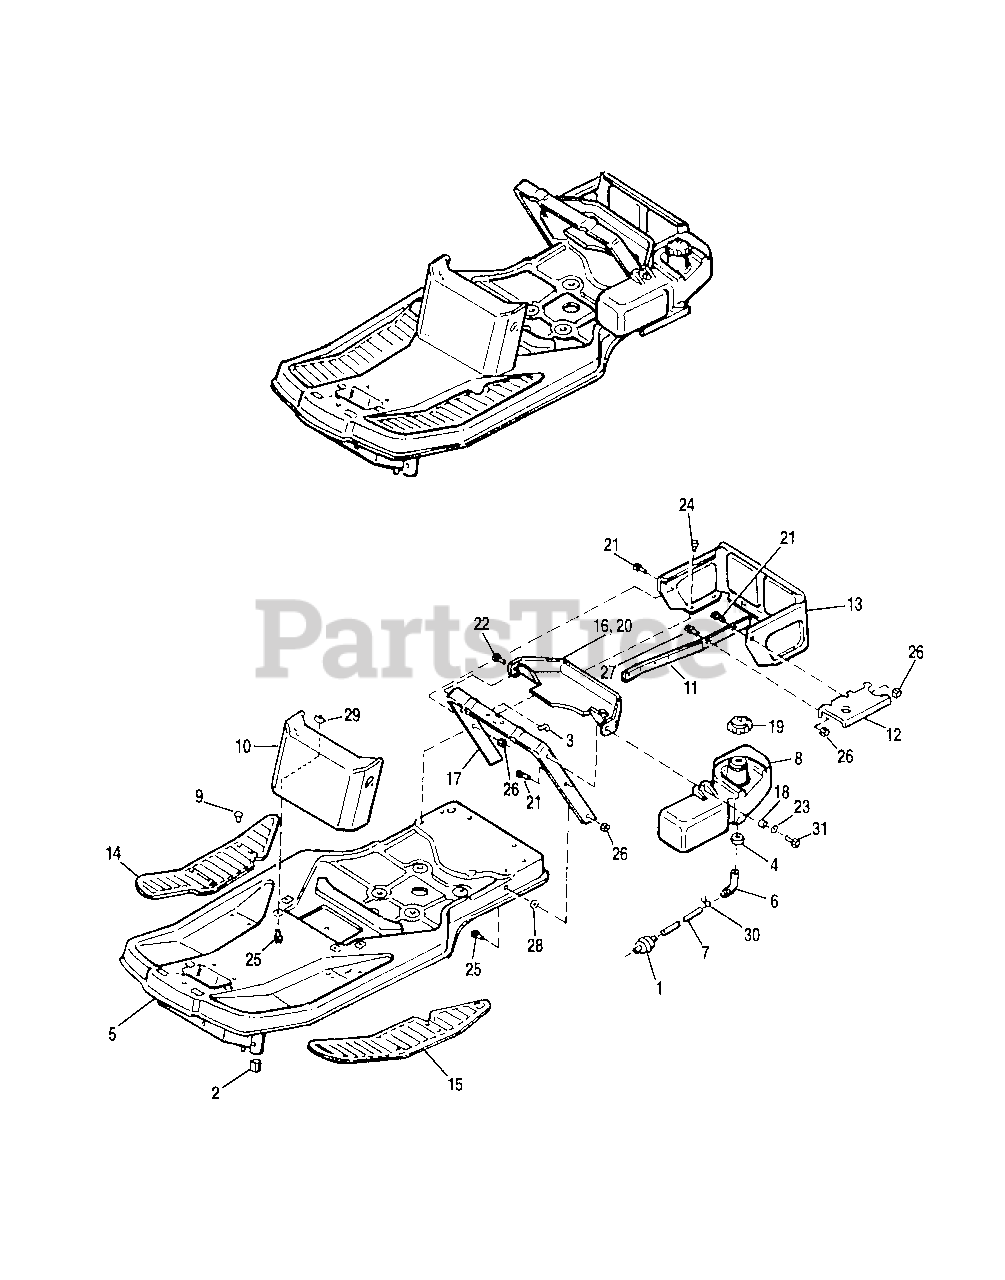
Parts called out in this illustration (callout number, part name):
1	FUEL FILTER
3	CLIP
4	BUSHING, Rubber
5	FRAME ASSY. (Incl. Ref. No. 2)
7	HOSE, Fuel Tank
8	FUEL TANK (Incl. Ref. Nos. 1, 4, 6 & 30)
10	PANEL, Front
11	STRAP, Fuel Tank, Brace
12	SUPPORT, Fuel Tank
13	SHROUD, Rear
14	PAD, Foot Rest, RH
15	PAD, Foot Rest, LH
16	DUCT, Air Inlet (Gear model only)
17	"U" SUPPORT, Seat Deck
18	SPACER, 21/64 x 1/2 x 21/64
19	CAP, Fuel Tank, Vented
20	DUCT, Air Inlet (Hydro model only)
21	CAPSCREW, Hex Hd., 5/16-18 x 1
22	SCREW, Hex Hd., Taptite, 5/16 x 1/2
23	WASHER, Plain, 13/32 x 7/8 x 5/64
24	SCREW, Hex Hd., Taptite, 1/4-20 x 1/2
25	CAPSCREW, Hex Hd., Whizlock, 5/16-18 x 3/4
26	NUT, Hex, Flange, Whizlock, 5/16-18
27	CARRIAGE BOLT, 5/16-18 x 3/4
28	PAL NUT, 5/16
29	PAL NUT, 5/16-18
30	CLAMP, Hose
31	SCREW, Taptite, 5/16-18 x 1
